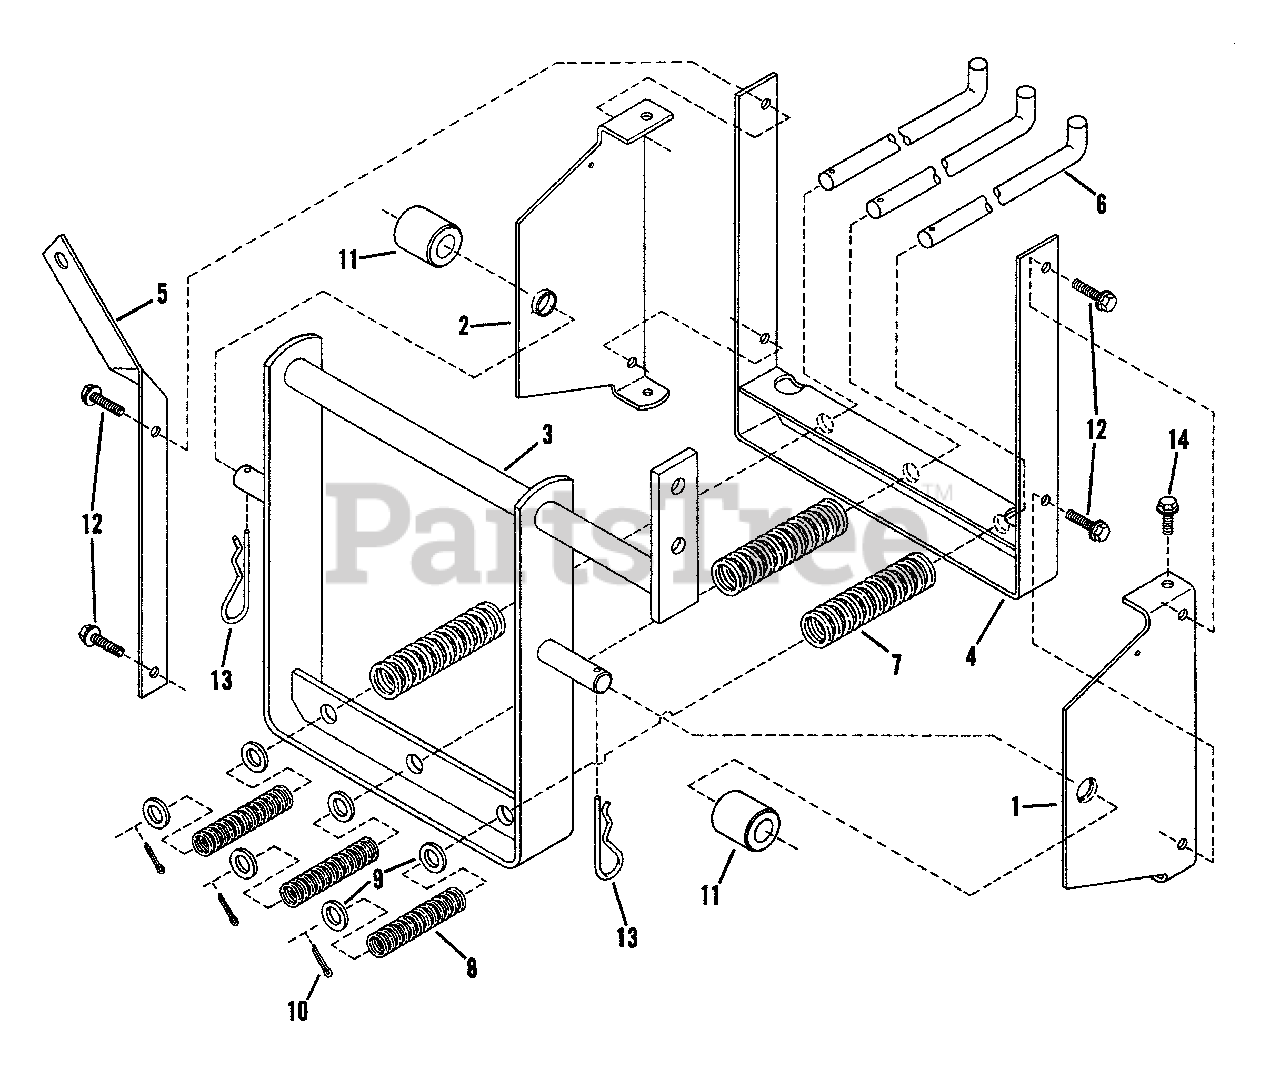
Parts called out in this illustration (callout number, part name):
1	BRACKET, Right Half Mounting
2	BRACKET, Left Half Mounting
3	STRUCTURE, Lift Yoke
4	STRUCTURE, Spring Strap
5	STRAP, Crank
6	PIN, Spring
9	WASHER, 1/2 Flat
10	PIN, 5/32x1" Cotter
11	BUSHING, Hitch
12	SCREW, 5/16-18x1" Hex Thread Forming
13	PIN, Cotter - Hair
14	SCREW, 5/16-18x5/8 Hex Thread Forming
